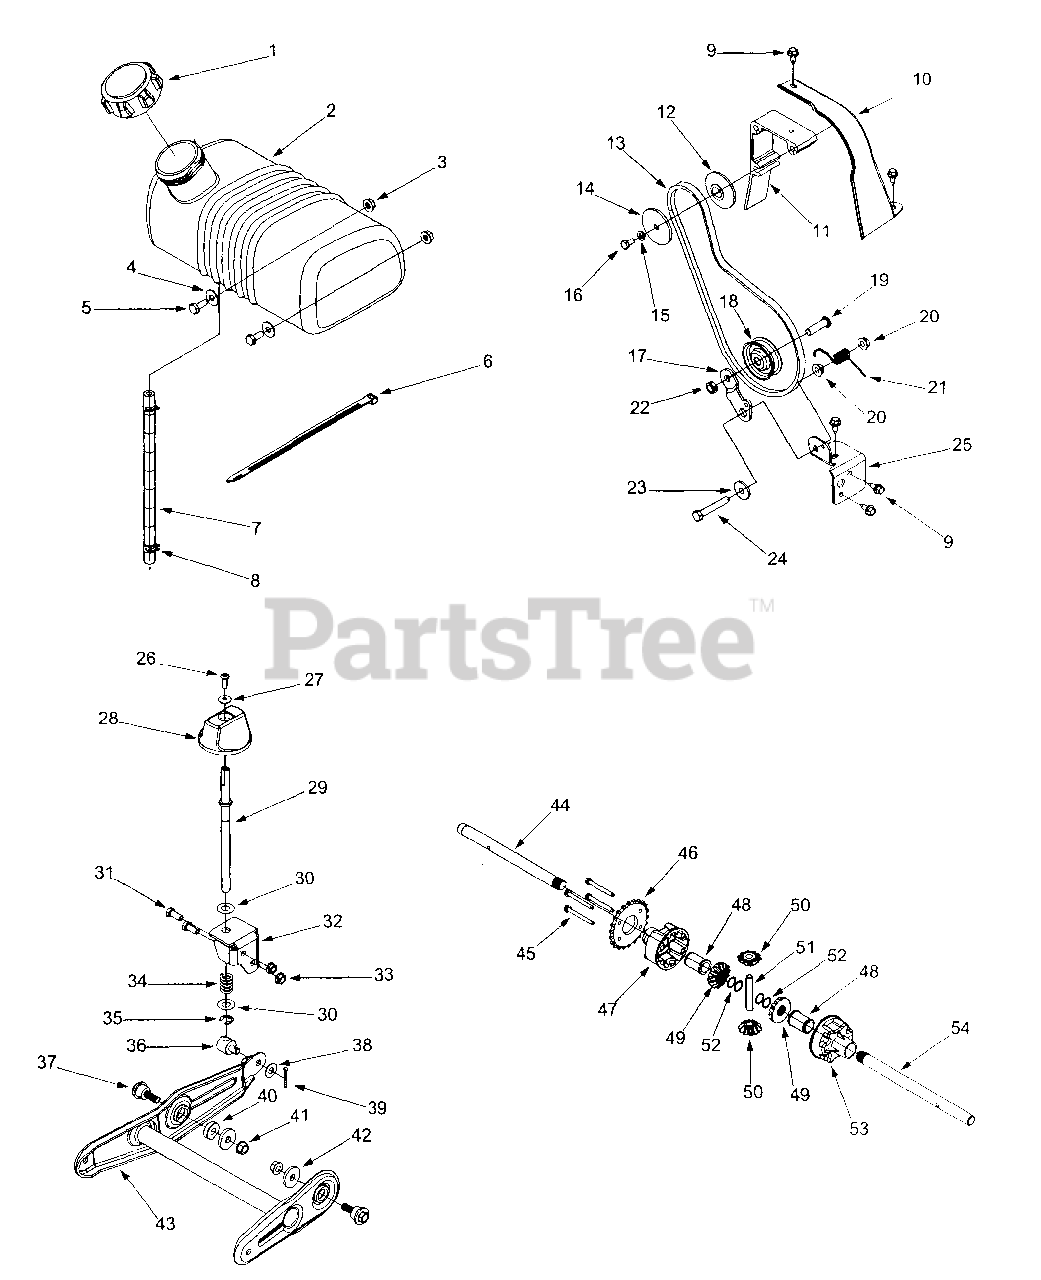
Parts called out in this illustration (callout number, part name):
1	Fuel Cap
2	Gas Tank - 1 Gallon
3	Hex Lock Nut 1/4-20
4	Flat Washer .28 ID x .74 OD
5	Hex Cap Screw 1/4-20 x .620
6	Cable Tie
7	Fuel Line
8	Hose Clamp
9	Hex Washer Screw 1/4-14 x .625
12	Pulley Half
13	V-Belt
14	Pulley Half
15	Lock Washer 1/4
16	Hex Cap Screw 1/4-28 x .50
17	Idler Bracket
18	Flat Idler
19	Hex Cap Screw 3/8-16 x 1.25
20	Hex Lock Nut 5/16-18
21	Torsion Spring
22	Lock Nut 3/8-16
23	Shoulder Spacer
24	Hex Cap Screw 5/16-18 x 2.0
27	Bell Washer .265 ID x .75 OD
29	Height Adjustment Rod
30	Flat Washer .508 ID x 1.0 OD
31	Hex Cap Screw 5/16-18 x .75
34	Compression Spring
35	E Ring
36	Adjustment Ferrule
37	Shoulder Screw 3/8-16
38	Flat Washer .406 ID x .875 OD
39	Cotter Pin
40	Spacer
41	Flange Lock Nut 3/8-16
42	Flat Washer .375 ID x 1.25 OD
45	Hex Washer Screw 1/4-20 x 2.375
46	Sprocket 22T
47	Differential Housing LH
48	Flange Bearing .75 ID x 1.0 OD x 1.5
49	Differential Gear 14T
50	Differential Gear 10T
51	Cross Shaft .427 x 2.7
52	Retaining Ring
53	Differential Housing RH
54	Axle Shaft .750 x 10.954
